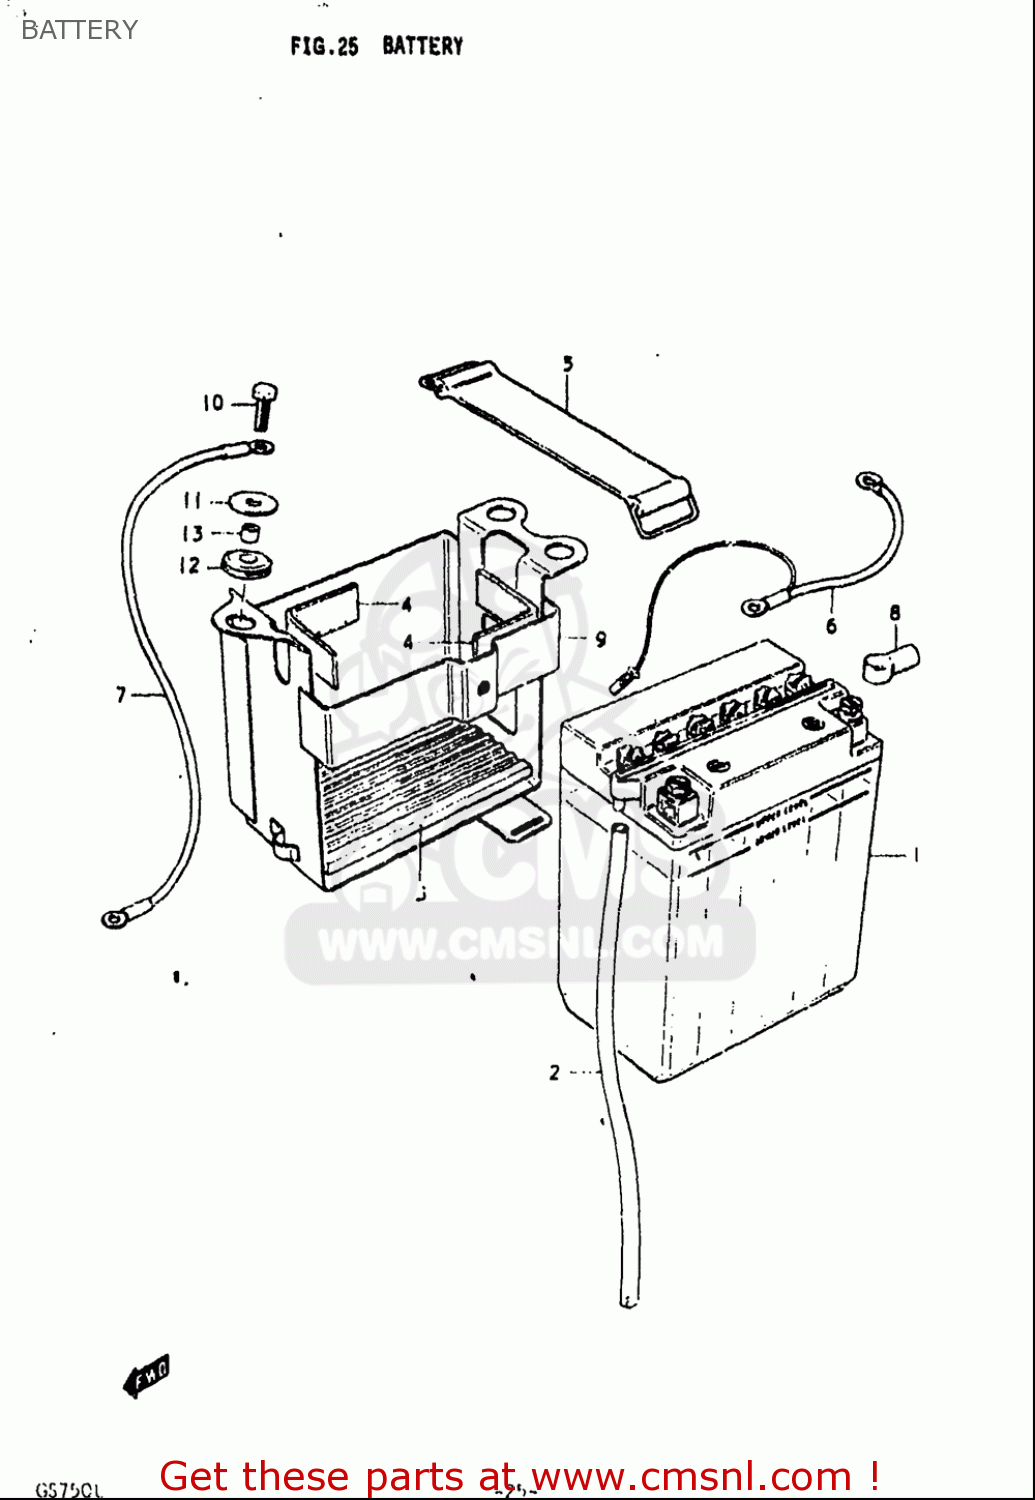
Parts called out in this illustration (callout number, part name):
1	BATTERY ASSY (12V)
2	HOSE,BATTERY EXHAUST(L:780)
3	PROTECTOR,BATTERY
4	PROTECTOR(170X95X3.0)
5	BAND
6	WIRE,BATTERY PLUS
7	LEAD WIRE,BATTERY(-)
8	CAP,TERMINAL
10	BOLT
11	WASHER(6.5X22X1.6)
12	CUSHION
13	SPACER(6.2X8.3X5.7)
